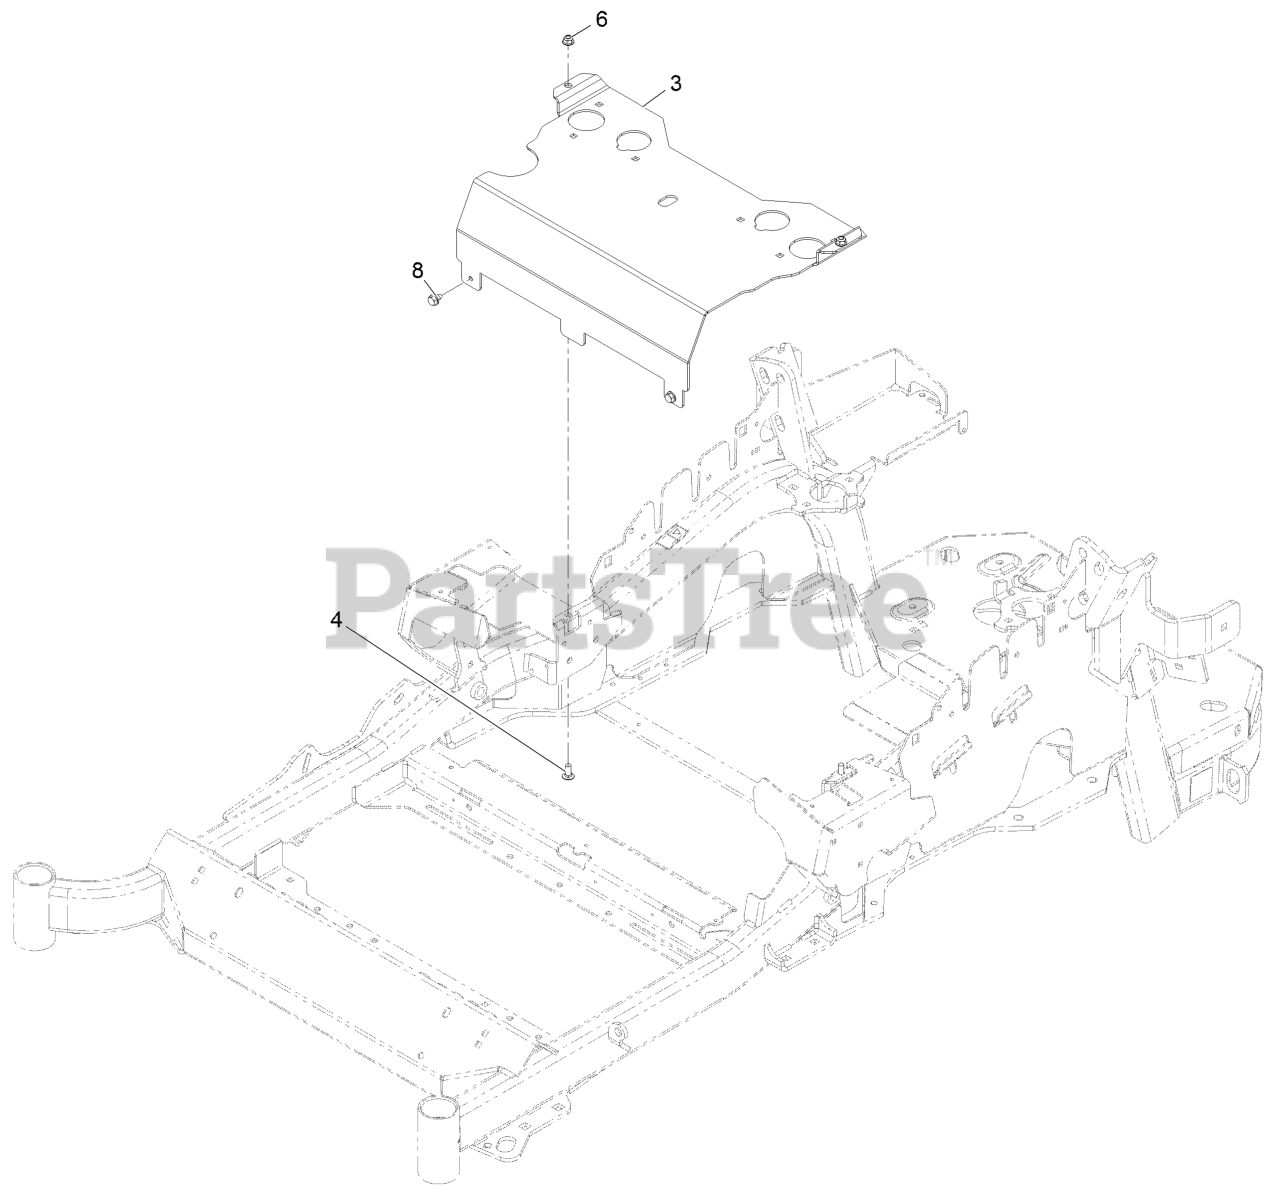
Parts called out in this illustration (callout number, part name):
3	Panel-Front, Seat Mount
4	SCREW-CARR
6	NUT-HF, NI
